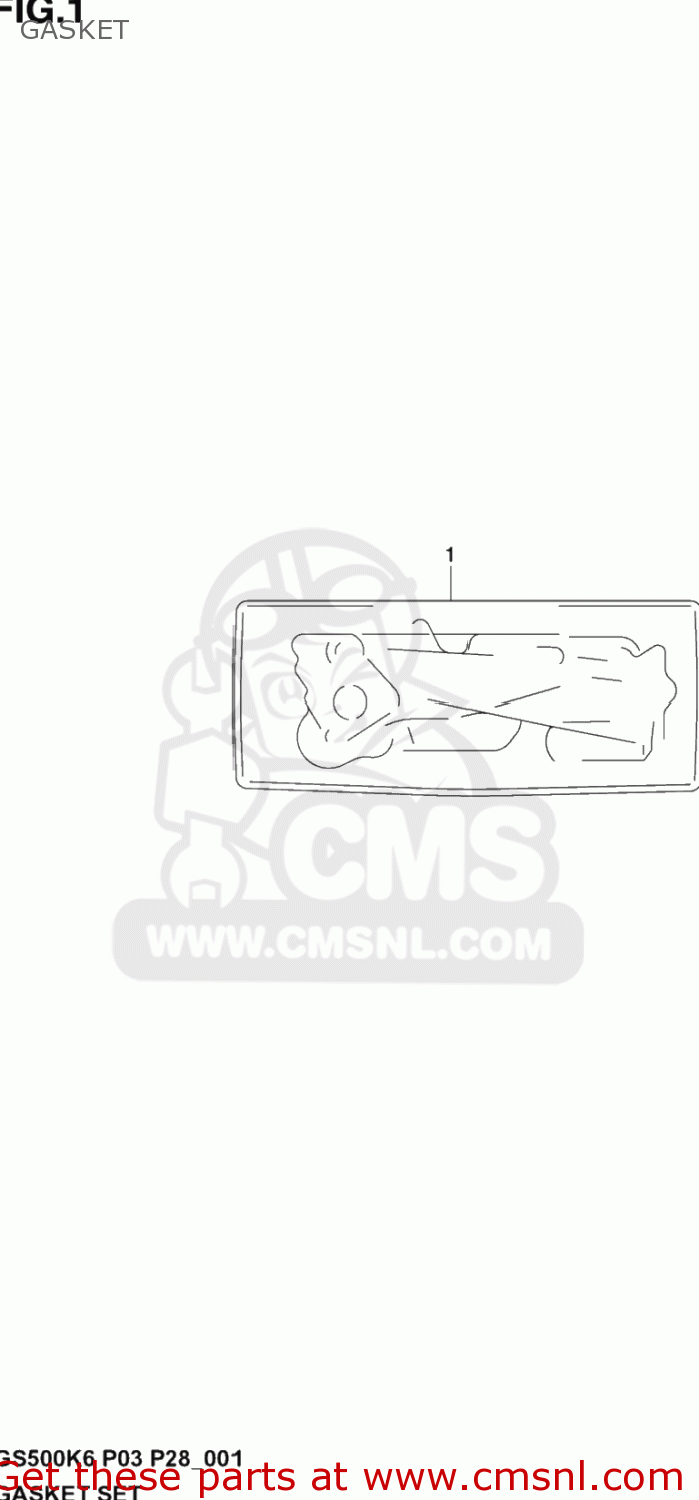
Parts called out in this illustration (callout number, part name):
1	GASKET SET (NAS)
2	GASKET,CYLINDER HEAD (NAS)
3	O RING,HEAD GASKET
4	GASKET,CYLINDER HEAD COVER (NAS)
5	GASKET,BREATHER COVER (NAS)
6	GASKET,CYLINDER (NAS)
7	GASKET,CLUTCH COVER (NAS)
8	GASKET,MAGNETO COVER (NAS)
9	GASKET,OIL PAN(ASB) (NAS)
10	GASKET,TENSIONER ADJUSTER (NAS)
11	GASKET,EXHAUST PIPE (NAS)
12	O RING,OIL FILTER CHAMBER CAP
13	GASKET(5.8X13X1.2) (NAS)
14	GASKET(8.2X14X1) (NAS)
15	GASKET(10.2X20X2).3 (NAS)
16	GASKET(14X19.2X2) (NAS)
17	O RING(D:1.05,ID:3.1)
18	O RING(D:1.9,ID:13)
19	O RING(D:1.9,ID:14.5)
20	O RING(D:3.1,ID:26.4)
21	O RING(D:2.4,ID:39.7)
